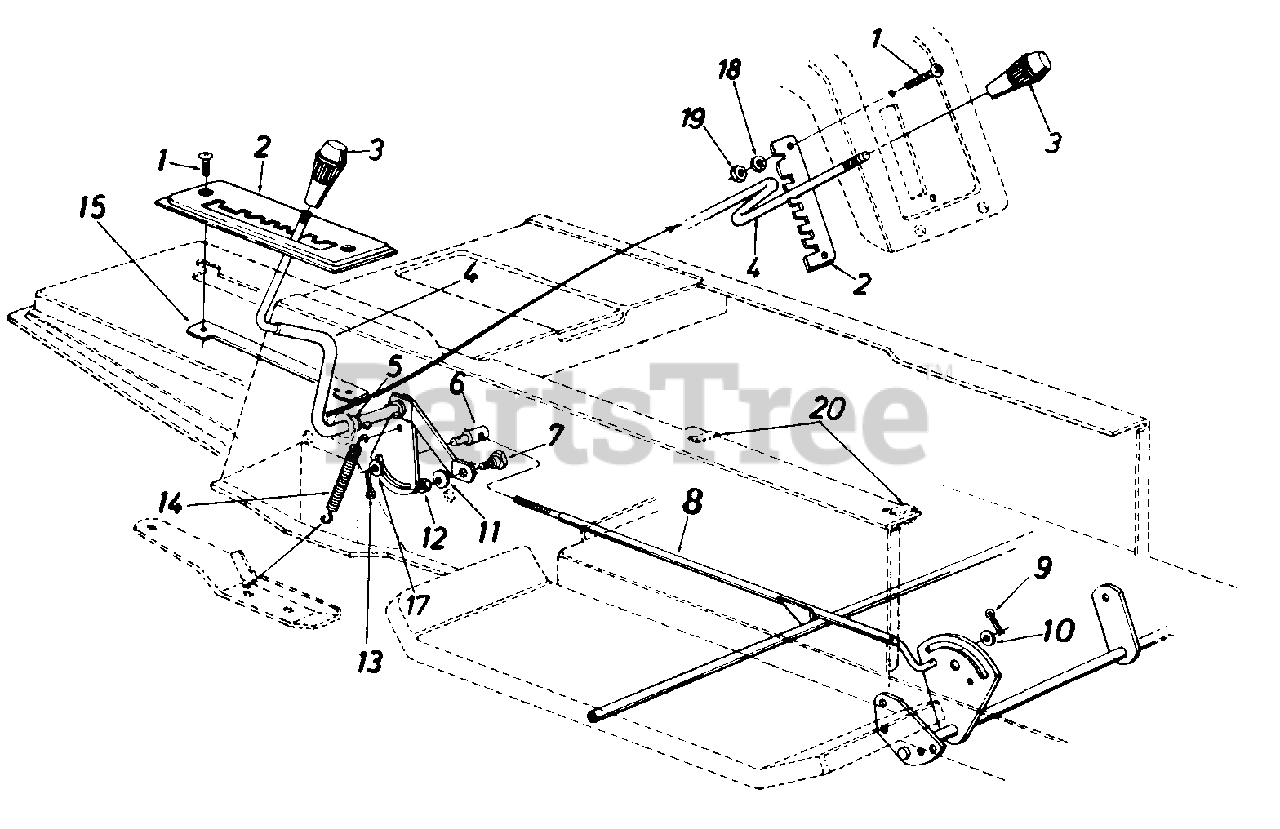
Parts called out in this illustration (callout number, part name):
1	Truss Mach. Scr. 1/4-20 x 75a Lg.
3	Shift Knob
4	Speed Selector Cam Ass'y.
5	Flat Washer .53" I.D. x .93"
6	Ferrule 3/8-24 x .37" Dia.
7	Shoulder Bolt .435" Dia. x .160
8	Speed Control Rod Ass'y.
9	Cotter Pin 3/32" Dia. x .75"
10	Fl-Wash. .469" I.D. x .88"
11	L-Wash. 5/16" I.D.
12	Hex Nut 5/16-18 Thd.
13	Cotter Pin 8132" Dia. x .75"
14	Spring .38" O.D. x 3.18" Lg.
15	Clamping Plate
17	Fl-Wash. .385" I.D. x .62"
18	L-Wash. 1/4" I.D.
19	Hex Nut 1/4-20 Thd.
20	Speed Clip
